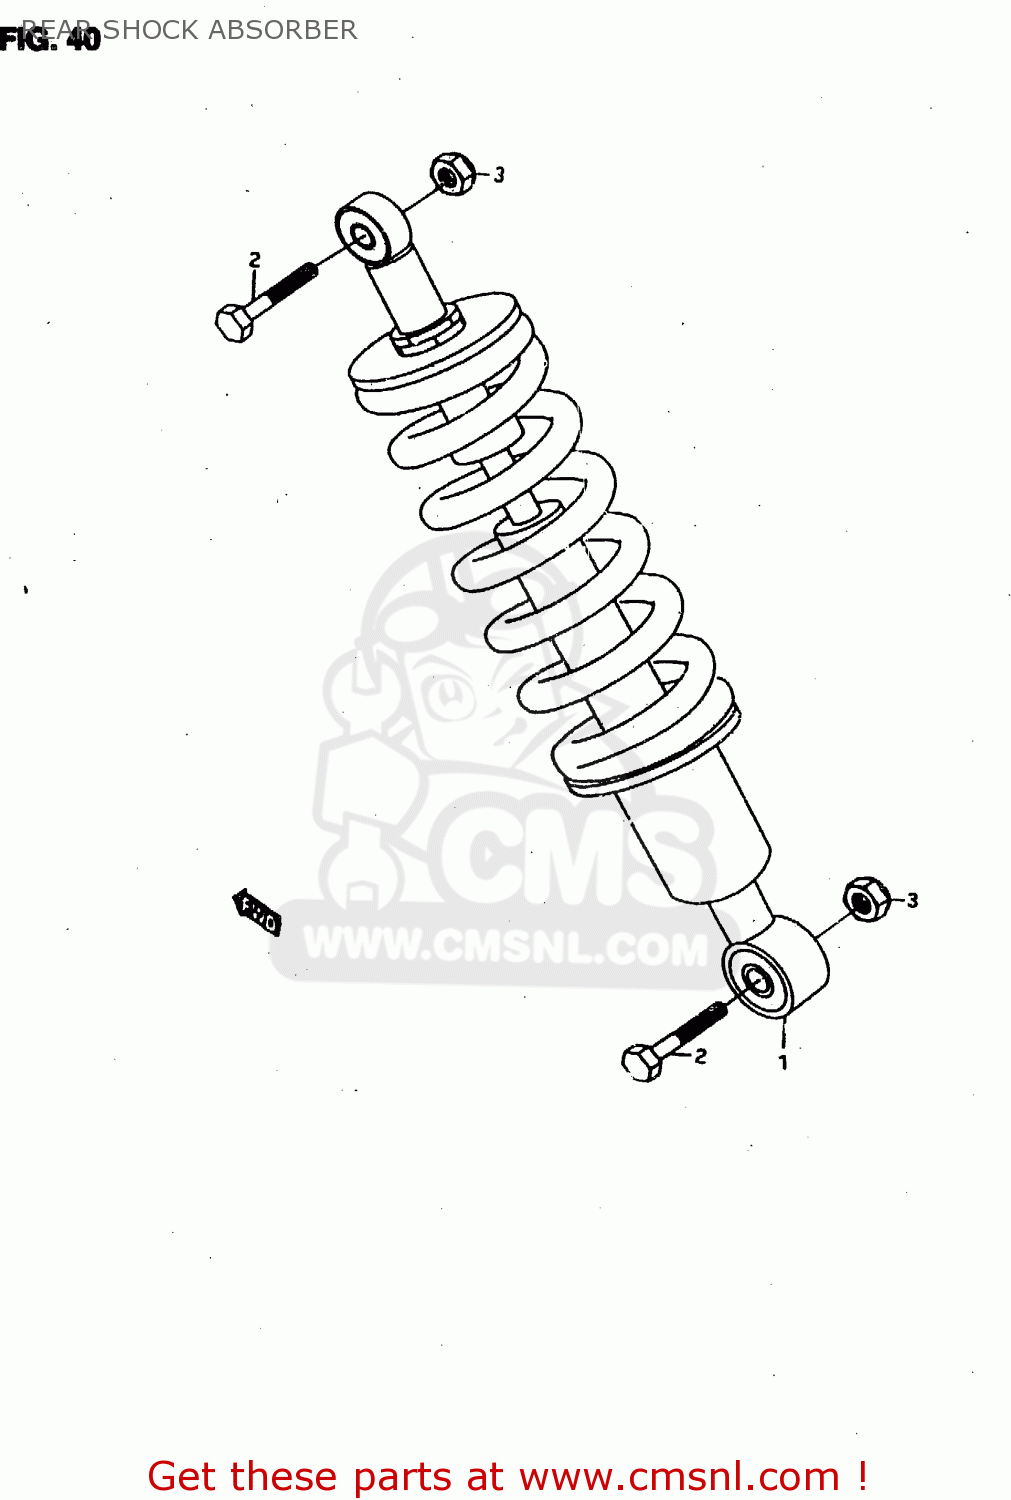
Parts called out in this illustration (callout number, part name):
1	ABSORBER ASSY, REAR
2	BOLT(10X48)
3	NUT 10MM
